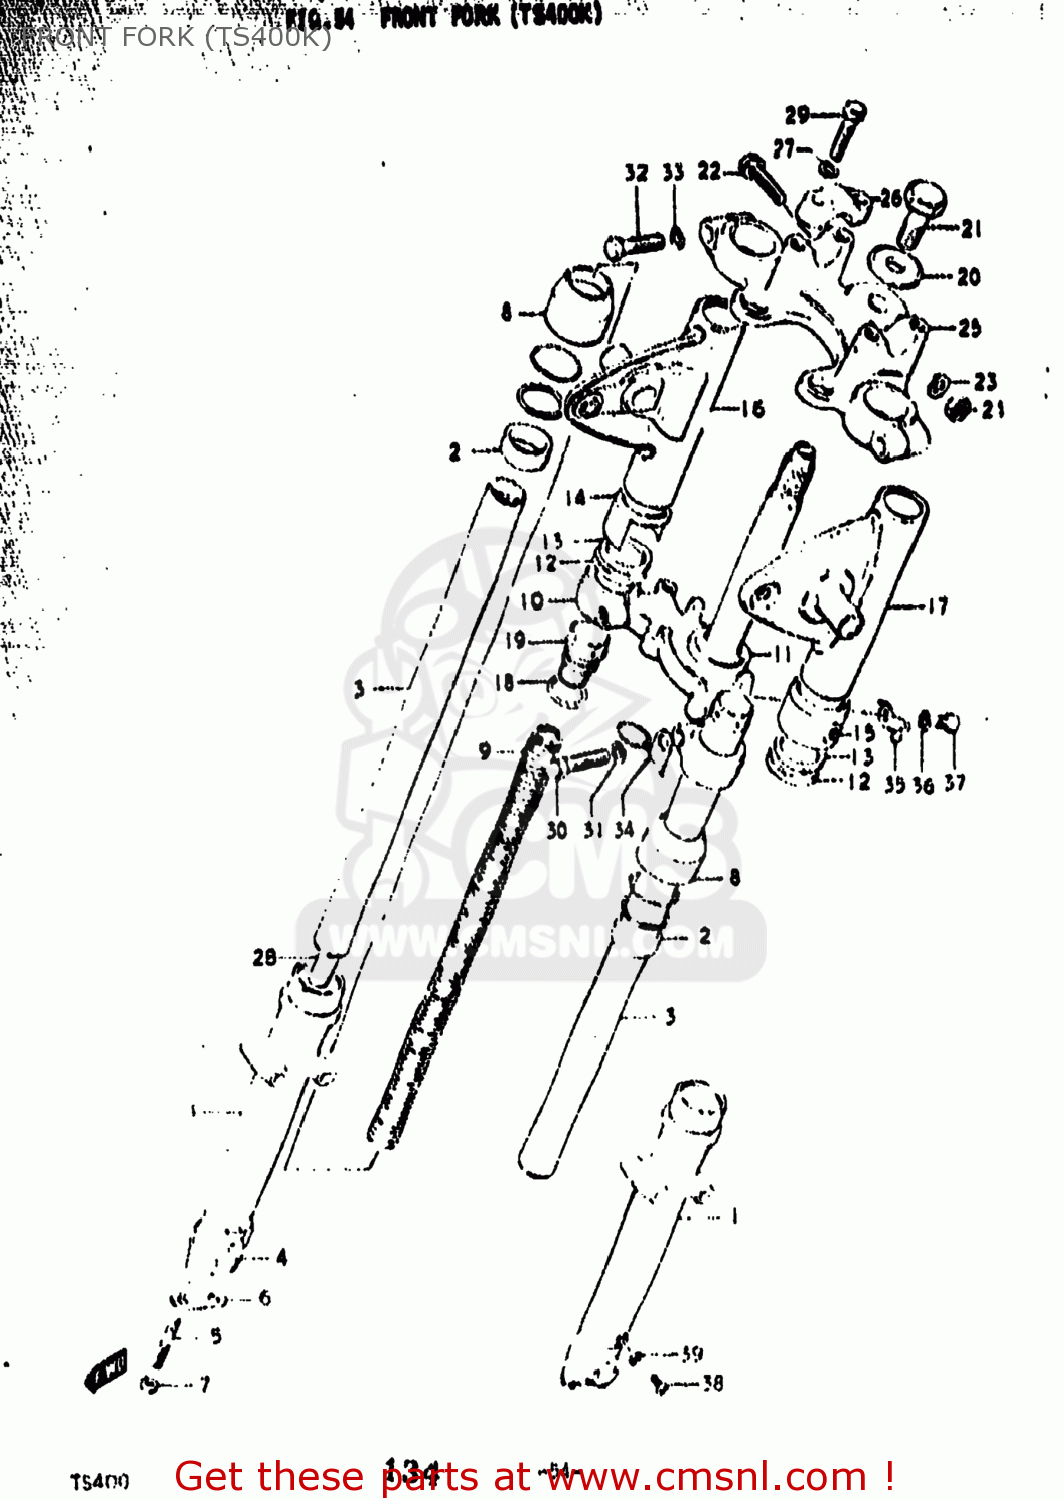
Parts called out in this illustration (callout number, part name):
1	TUBE,OUTER,RIGHT
2	SEAL,OIL
3	TUBE,FORK,INNER
4	HOLDER,AXLE
5	STUD BOLT
7	NUT
8	DUST SEAL,FRONT FORK
9	SPRING,FRONT FORK
10	STEM,STEERING
11	RACE,STEERING OUTER LWR
12	GUIDE, COVER
13	CUSHION,HEADLAMP BRACKET
14	CUSHION,HEADLAMP BRACKET
16	BRACKET,HEADLAMP HOUSING
17	BRACKET,HEADLAMP,LEFT
18	O RING
19	CAP,FORK INNER TUBE
20	WASHER
21	BOLT,FORK INNER TUBE
22	BOLT,FORK INNER TUBE F
23	LOCK WASHER
24	NUT
25	HEAD,STEERING STEM
26	HOLDER,HANDLEBAR
27	LOCK WASHER
28	CYLINDER,FRONT FORK
29	BOLT
30	BOLT,FR FORK LWR(12X33)
31	WASHER,LOCK 12
32	BOLT,FORK INNER TUBE F
33	LOCK WASHER
34	GUIDE,CABLE
35	CLIP
36	LOCK WASHER
37	SCREW
38	SCREW
39	GASKET,DRAIN,PLUG (NAS)
